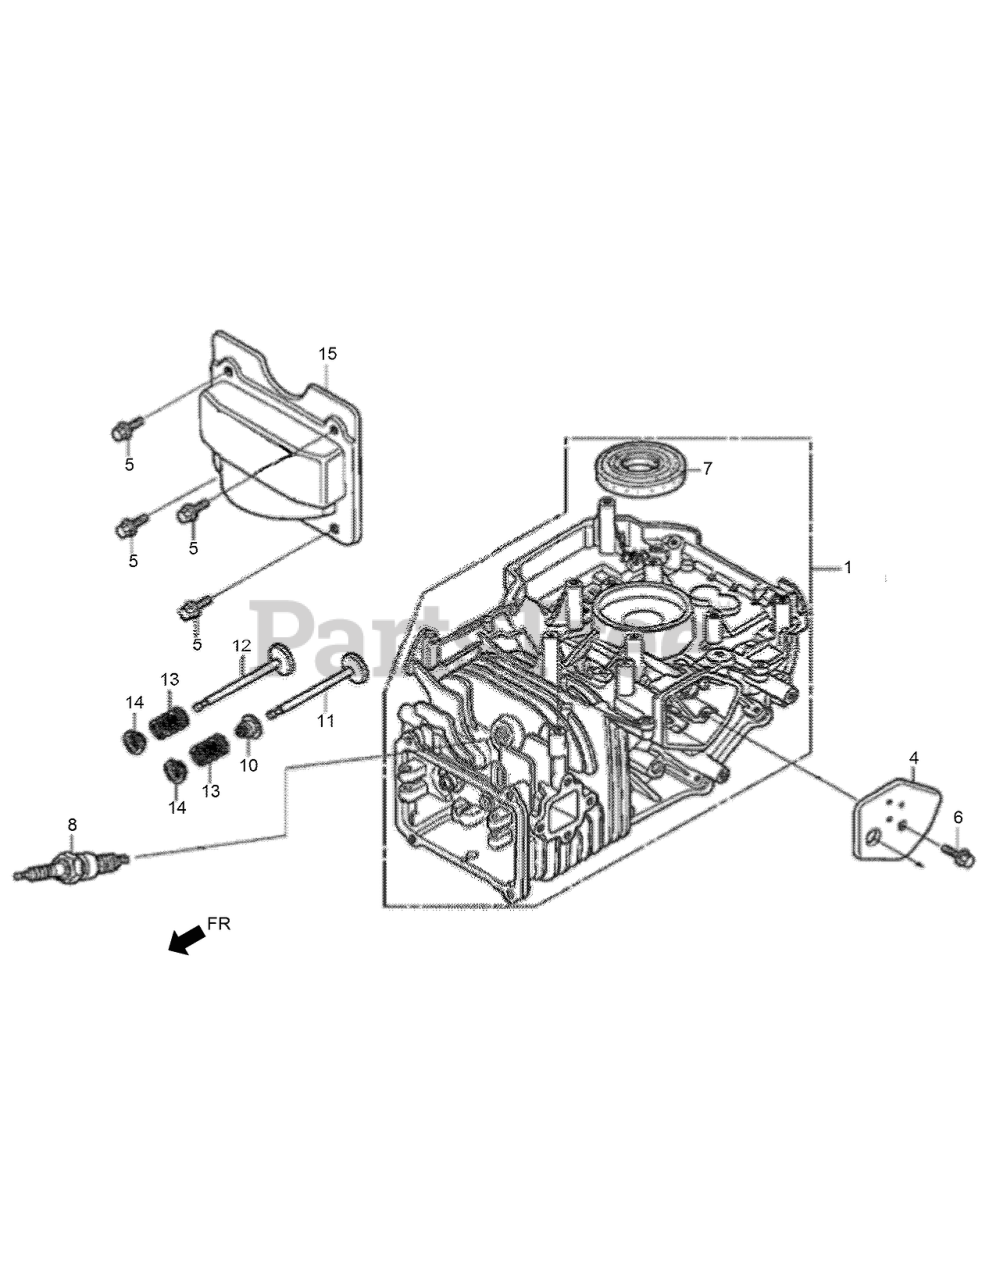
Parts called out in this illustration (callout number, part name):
1	BARREL ASM-CYLINDER
4	BREATHER COVER ASM
5	BOLT-FLANGE-6X12
6	BOLT-FLANGE-6X14
7	OIL SEAL-25.4X62X6
8	PLUG-SPARK NGK]
10	SEAL-VALVE STEM
11	VALVE-INTAKE
12	VALVE-EXHAUST
13	SPRING-VALVE
14	RETAINER-VALVE SPRING
15	COVER-HEAD
